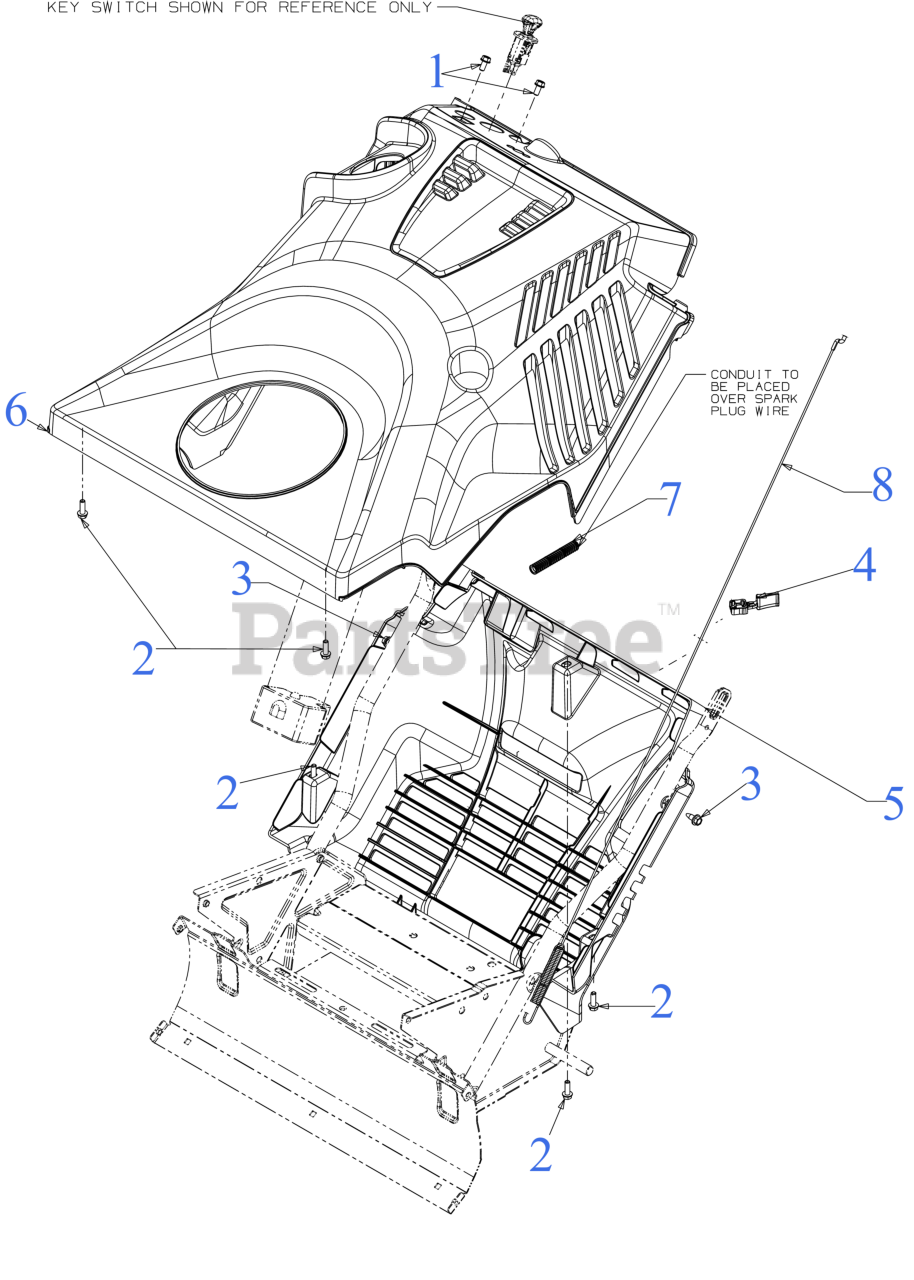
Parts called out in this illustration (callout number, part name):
1	HEX SCREW 1/4-15 x .50
2	SCREW 1/4-15 x .750
3	SCREW 1/4-20X.625
4	CHOKE EXTENION LEVER
5	BOTTOM COVER
6	COVER (D-STYLE)
7	CONVOLUTED CONDUIT
8	AUGER CLUTCH CABLE 37.05"
